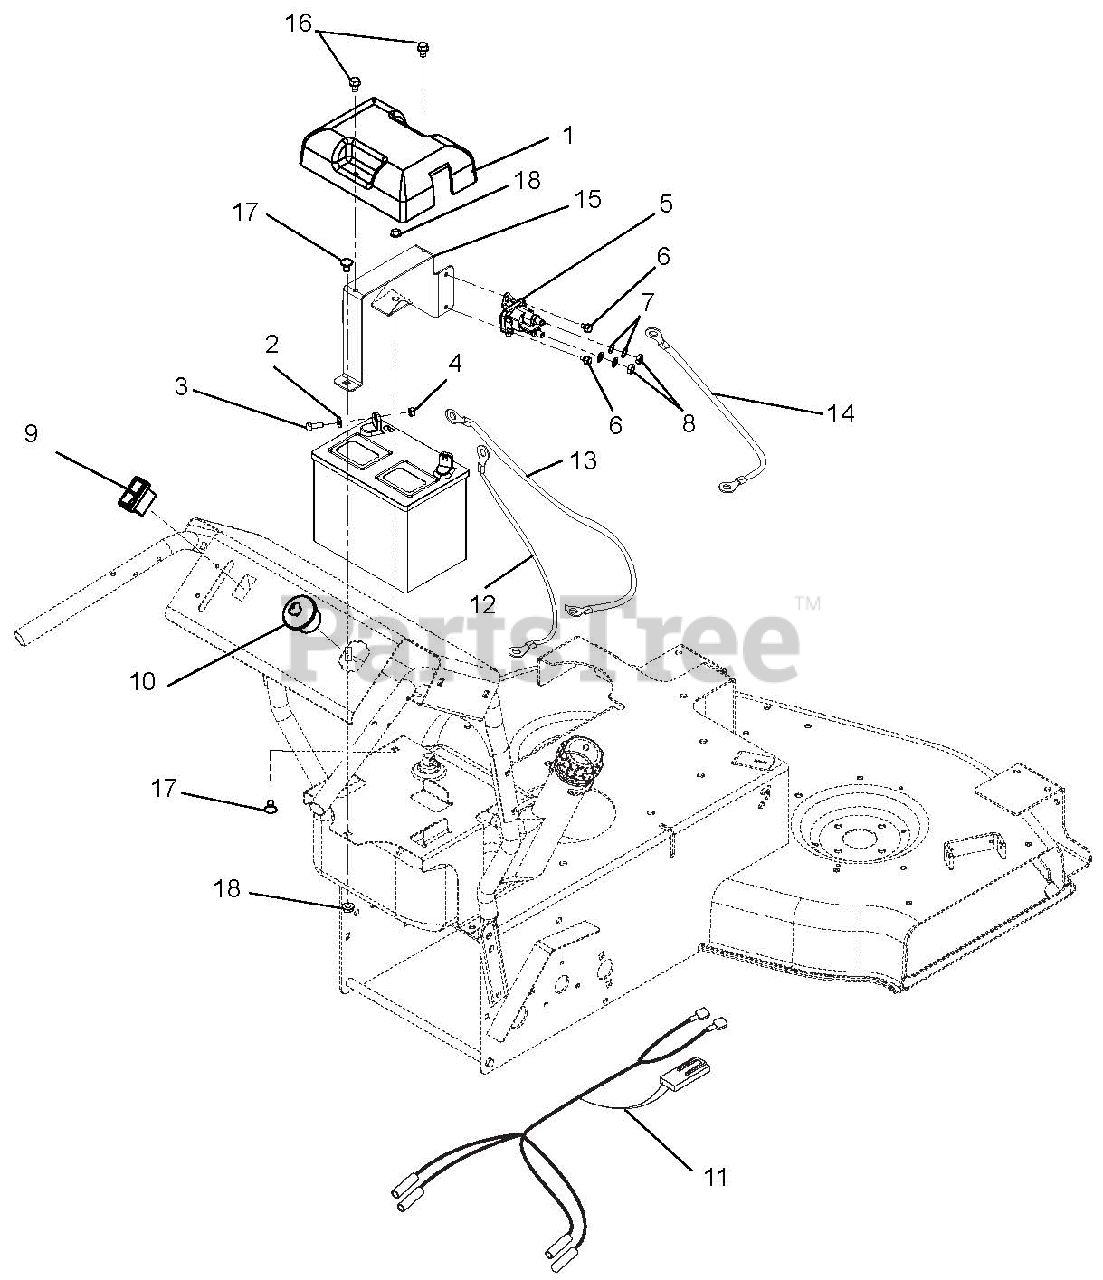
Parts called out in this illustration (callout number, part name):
1	COVER, BATTERY
2	@WSHR-FL-STL.281X.62X.065 YWZC
3	@BLT-HEX .25-20X.75 GR5 YWZC
4	NUT-KEPS .250-20
5	SOLENOID
6	@SCR-TAP .25-20X.37 HWH YWZ TR
7	WSHR-LOCK INT .31 YWZC
8	NUT-JAM .31-24 YWZC
9	SWITCH-ROCKER, MOMENTARY
10	KEYSWITCH-IGNITION 3 POS
10	BRKT, STRIPER MOUNT-RIGHT
11	HARNESS, WAW WIRING
12	CABLE, POS. BAT 18.50"
13	CABLE, GROUND 22.0"
14	CABLE, POS. BAT 6.75"
15	BRKT, BATTERY MOUNT
16	@SCR-TAP .31-18X.50 HWH TR YWZ
17	@BLT-RDHDSQNK .31-18X.50 G5YZ
18	@NUT-LK-TOP-FLG .31-18 YWZC
